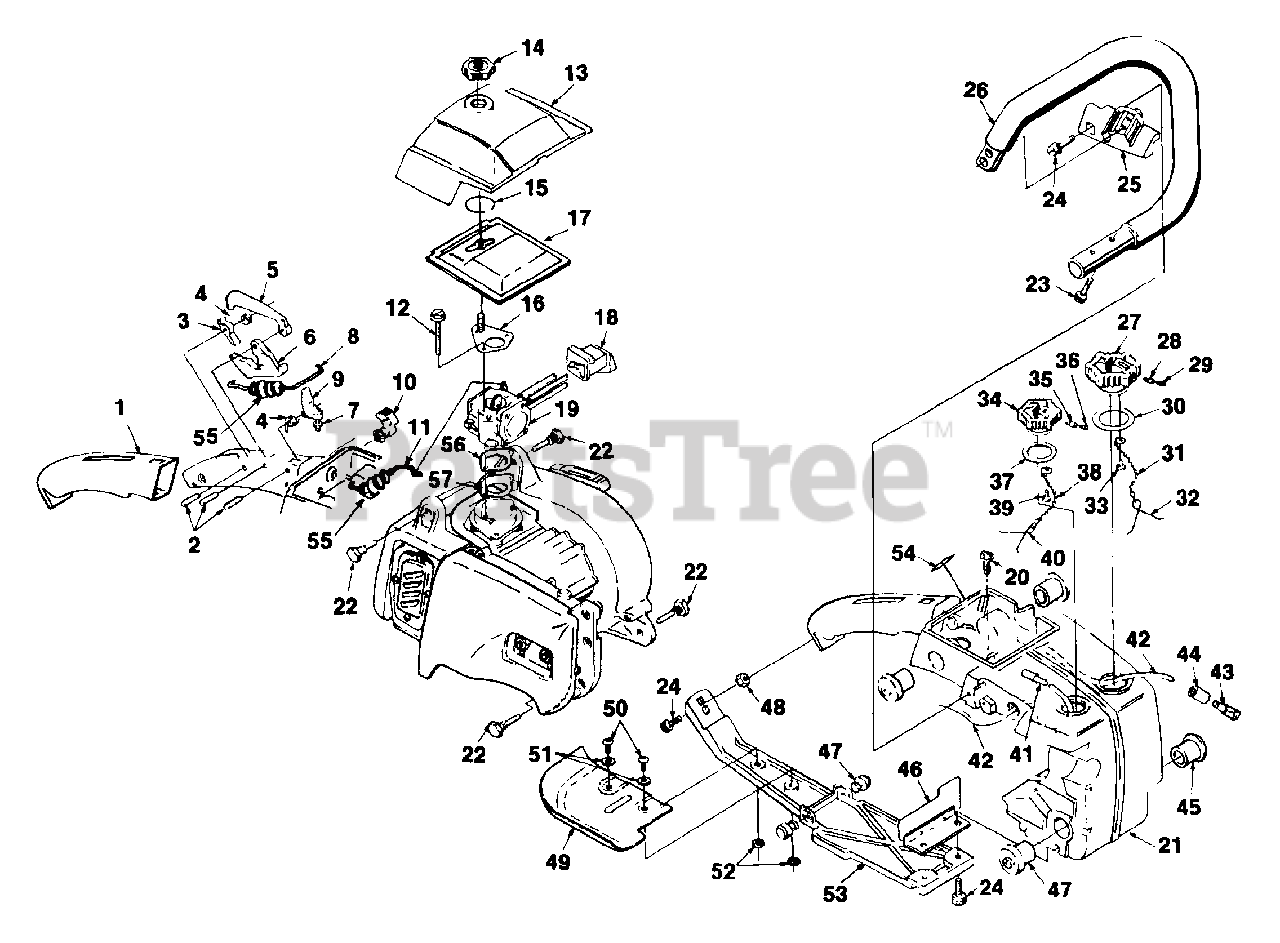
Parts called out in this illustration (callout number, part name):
1	GRIP-Throttle handle
2	PIN-Dowel
3	LEVER-Trigger lock
4	SPRING-Torsion
5	LOCK-Trigger
6	KIT-Trigger & Screw
7	SCREW-Trigger latch
8	ROD-Throttle
9	LATCH-Trigger
10	KNOB-Choke
11	ROD-Choke
12	SCREW-Hex sems (10-24 x 1 3/4")
13	AIR FILTER COVER
14	NUT-Filter cover mounting
15	RING-Retaining
16	BRACKET-Mounting cover
17	FILTER-Air
18	GROMMET-HI-LO
19	CARBURETOR-(HDC-39-A)
20	SCREW-Hex sems (10-24 x 5/16")
21	HOUSING-Engine
22	PIN-Isolator
23	SCREW-Soc. hd. (10-24 x 7/8")
24	SCREW-Hex sems (10-24 x 3/4")
25	BRACKET-Handle bar
26	HANDLEBAR
27	CAP-Fuel filler
28	VALVE-Check (oval duckbill)
29	FILTER-Filler cap
30	GASKET-Fuel cap
31	CHAIN-Bead
32	RETAINER
33	SCREW-Pan hd. plastite (6 x 1/4")
34	CAP-Oil filler
35	VALVE-Check (oval duckbill)
36	FILTER-Filler cap
37	GASKET-Oil cap
38	CHAIN-Bead
39	SCREW-Pan hd. plastite (6 x 1/4")
40	RETAINER-Cap
41	FINDER-Oil
42	TUBING-Rubber (10 1/2")
43	FUEL PICK-UP
44	FILTER-Felt
45	SET-Isolator (soft) (set of four)
46	DEFLECTOR-Air (exhaust)
48	NUT-Hex (10-24)
49	KIT-Right hand guard
50	SCREW-Hex hd. cap
52	NUT-Center lock (#10-24)
53	BRACE-Handle
54	DECAL-Choke
55	GROMMET
56	BUSHING
